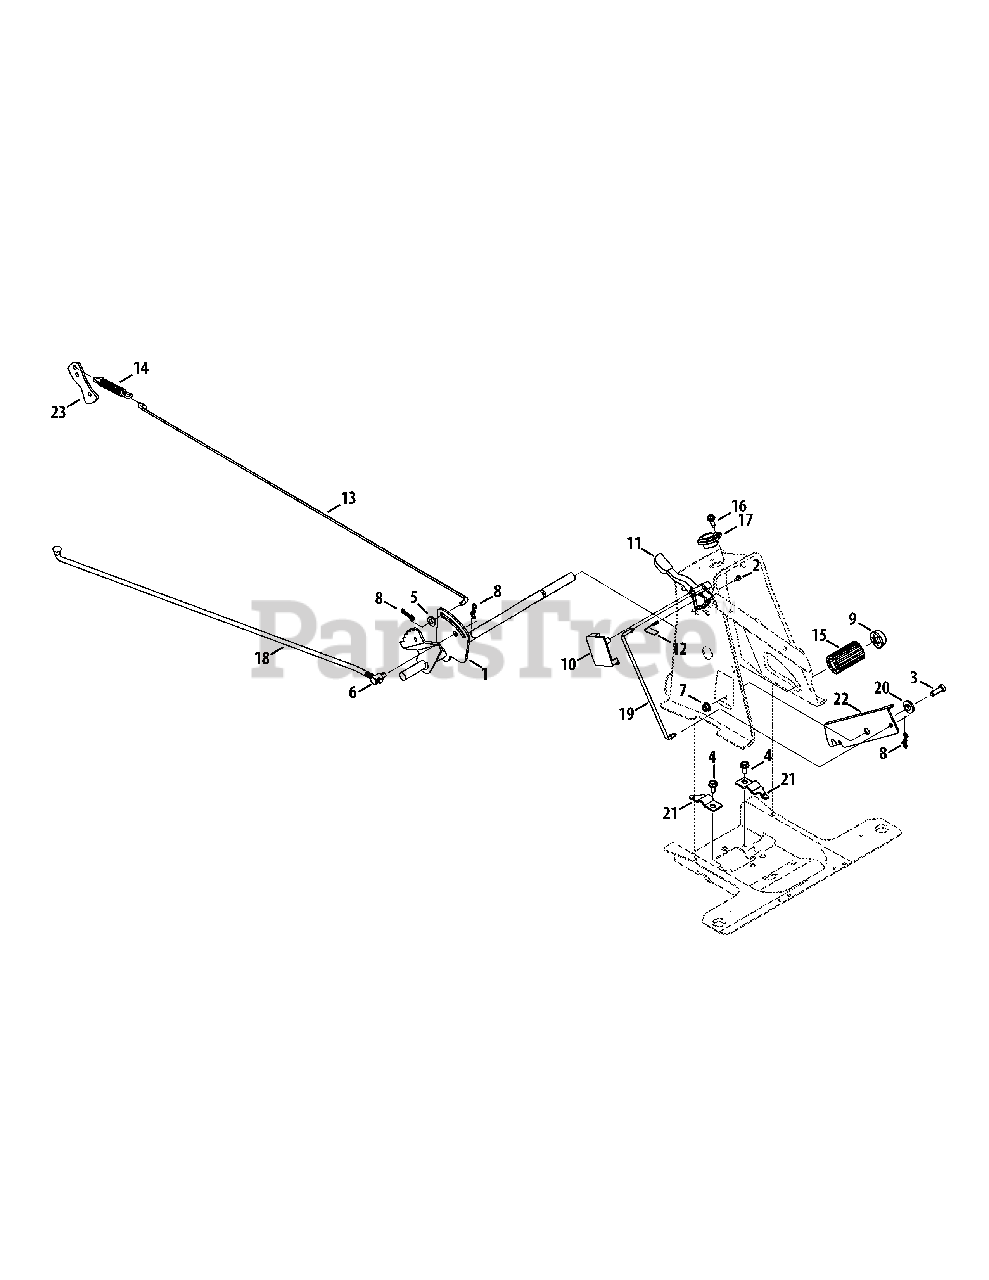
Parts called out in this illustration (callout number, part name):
1	Brake Pedal Assembly
2	Screw, #10-16:0.500
3	Hex Head Scerw, 5/16-18:1.00
4	Tap Screw, 5/16-18:.750
5	Flat Washer, .330 x .630 x .064
6	Ferrule 3/8-24 X .375 Dia.
7	Flange Lock Nut, 5/16-18
8	Bow-Tie Cotter Pin, 72
9	Push Cap, 5/8
10	Speed Control Cover
11	Speed Lever, 6-SPEED
12	Shift Spring
14	Extension Spring, .59 OD x 4.00 LG
15	Foot Pad, 2.5" LG.
16	Shoulder Screw, .368 X.113, 1/4-20
17	Steering Col. Bearing, .880 ID X 1.36
18	Variable Speed Control Rod
19	Speed Selector Control Rod
20	Shoulder Spacer
21	Pedal Strap Support Bracket, 5/8
22	Speed Latch Bracket
23	Brake lever Bracket
